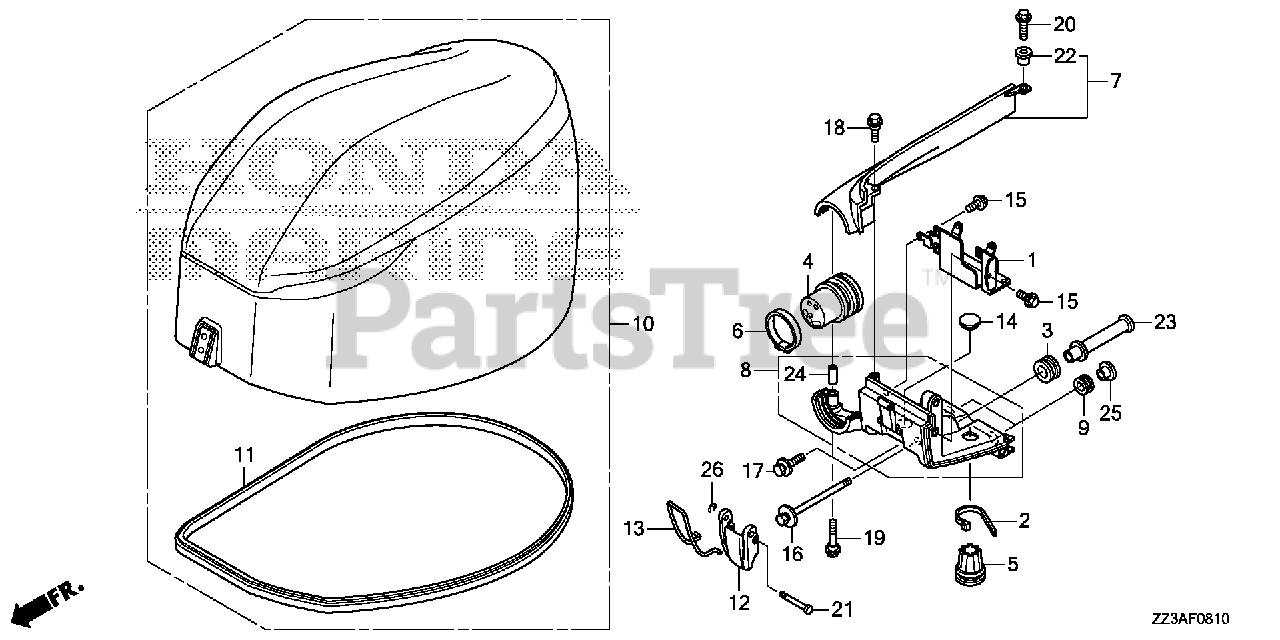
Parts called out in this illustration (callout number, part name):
1	BRACKET, REMOTE CONTROL CABLE
2	BAND (BLACK 3.5X140)
3	GROMMET, CASE (LOWER)
4	GROMMET, REMOTE CONTROL CABLE
5	GROMMET, CASE (LOWER) (C)
6	BAND, CASE GROMMET (LOWER)
7	COVER, FR. SEPARATE *NHB14M* (AQUA MARINE SILVER METALLIC)
8	BRACKET, FR. COVER (LOWER) *NHB14M* (AQUA MARINE SILVER METALLIC)
9	RUBBER, FENDER MOUNTING
10	COVER ASSY., ENGINE *NHB14M* (AQUA MARINE SILVER METALLIC)
11	SEAL, ENGINE COVER
12	LEVER, FASTENER
13	WIRE, FASTENER
14	CAP, L. SIDE COVER
15	BOLT, FLANGE (6X10)
16	BOLT-WASHER (6X95)
17	BOLT-WASHER (6X27)
18	BOLT, SPECIAL (6X17)
19	BOLT, SPECIAL (6X37)
20	BOLT, FLANGE (6X20)
21	PIN (5X44.5)
22	COLLAR, DISTANCE (6.5X9X11.5)
23	COLLAR, FR. BRACKET
24	COLLAR, DISTANCE (6.1X9.1X20.5)
25	COLLAR, DISTANCE (6.2X7.5)
26	E-RING (4MM)
